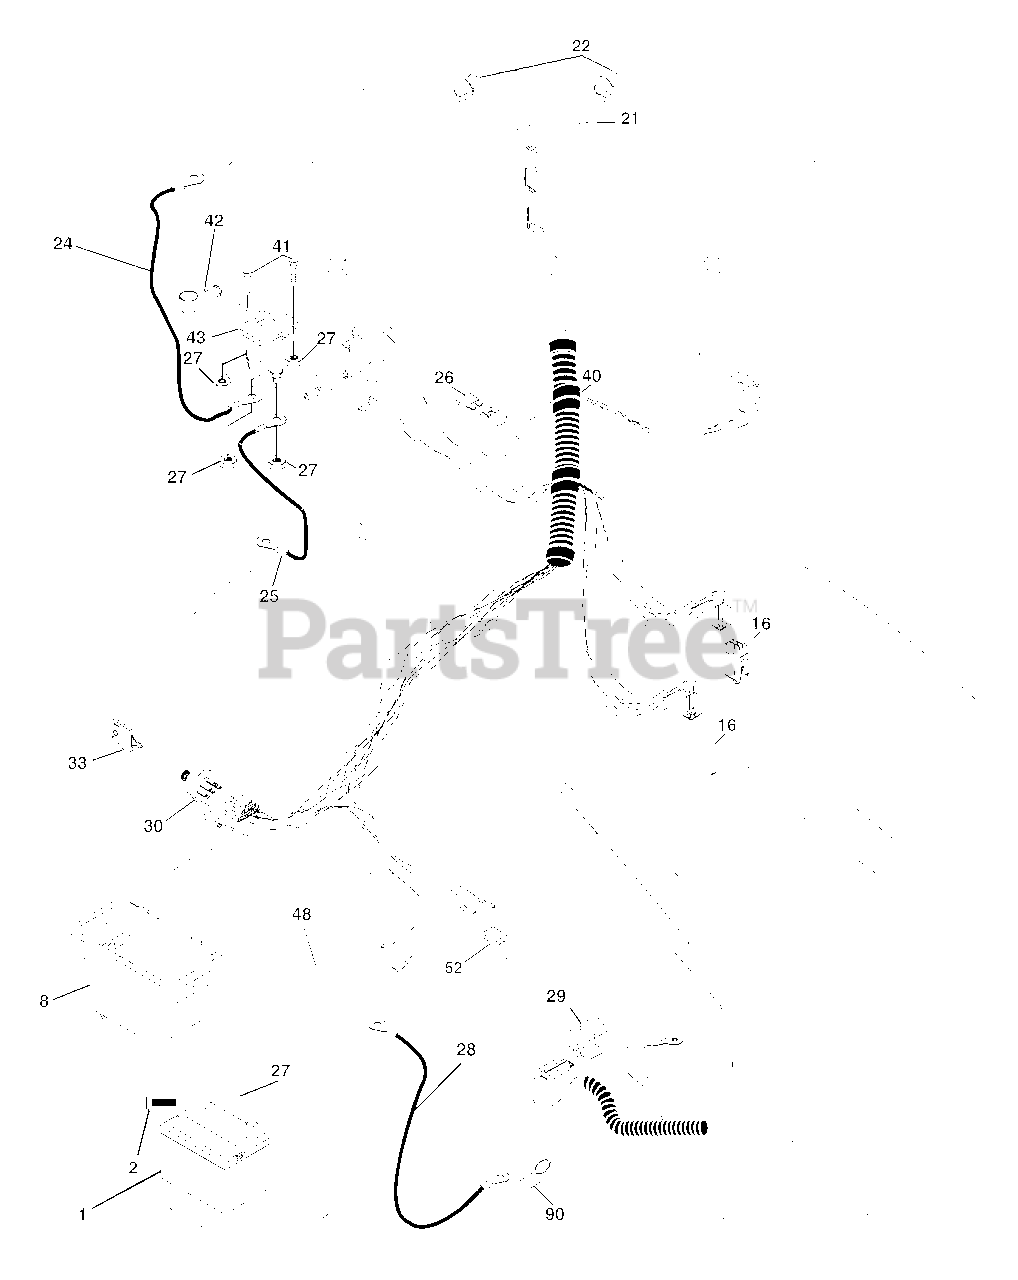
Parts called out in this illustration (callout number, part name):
1	Battery
2	Bolt Hex Hd 1/4-20unc X 3/4
8	Box Battery
16	Switch Interlock
21	Harness Asm Light W/4152j
22	Bulb Light #1156
24	Cable Battery 6 Ga 11"red
25	Cable Battery
26	Fuse 20 AMP
27	Nut Keps Hex 1/4-20 Unc
28	Cable Ground 6 Ga 12"black
29	Switch Plunger Nc Gray
30	Switch Ign
33	Key Ign
40	Harness Ign
41	Bolt Blk Fin Hex 1/4-20
42	Cover Terminal Red
43	Solenoid
48	Adapter Ammeter
52	Protection Wire Loop
90	Cover Terminal Battery
